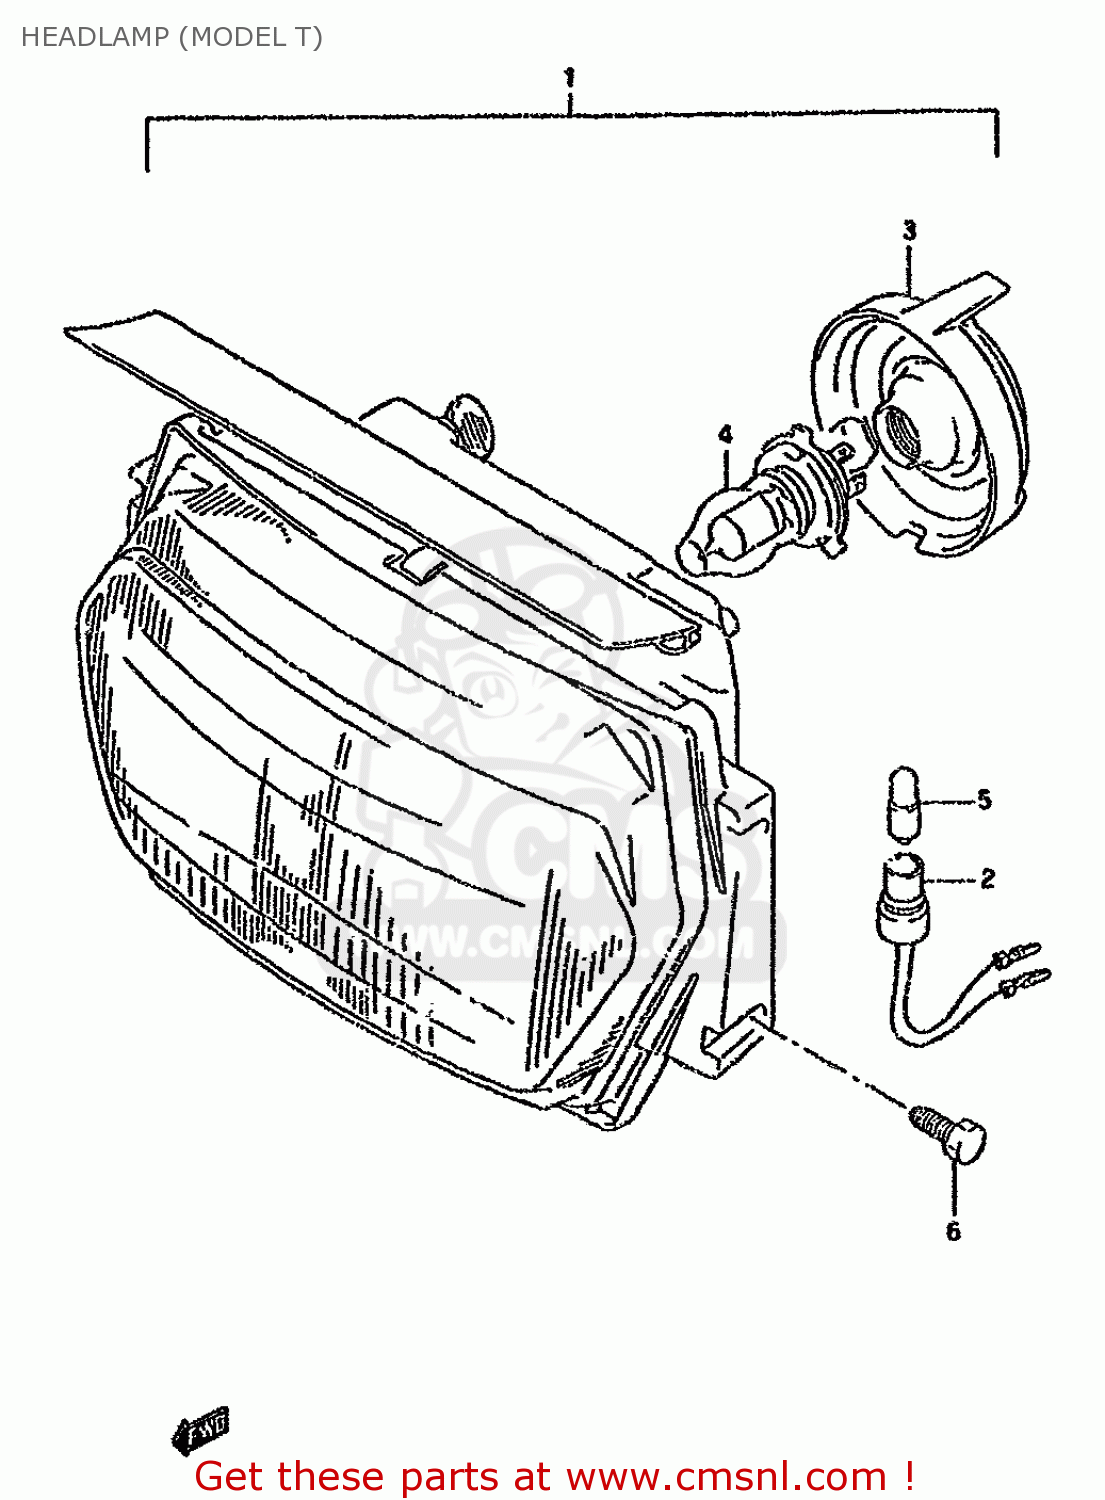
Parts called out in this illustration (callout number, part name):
1	HEADLAMP ASSY
2	SOCKET
3	COVER,SOCKET
4	BULB(12V60/55W,H4)
5	BULB(12V4W)
6	BOLT
7	BULB(12V60/55W,H4)
8	BULB(12V4W)
9	BOLT
10	BOLT
11	LOCK WASHER
12	WASHER
13	REFLECTOR,REFLEX FR
14	BRACKET,FR SIDE RR,R
15	BRACKET,FR SIDE RR,L
16	NUT
